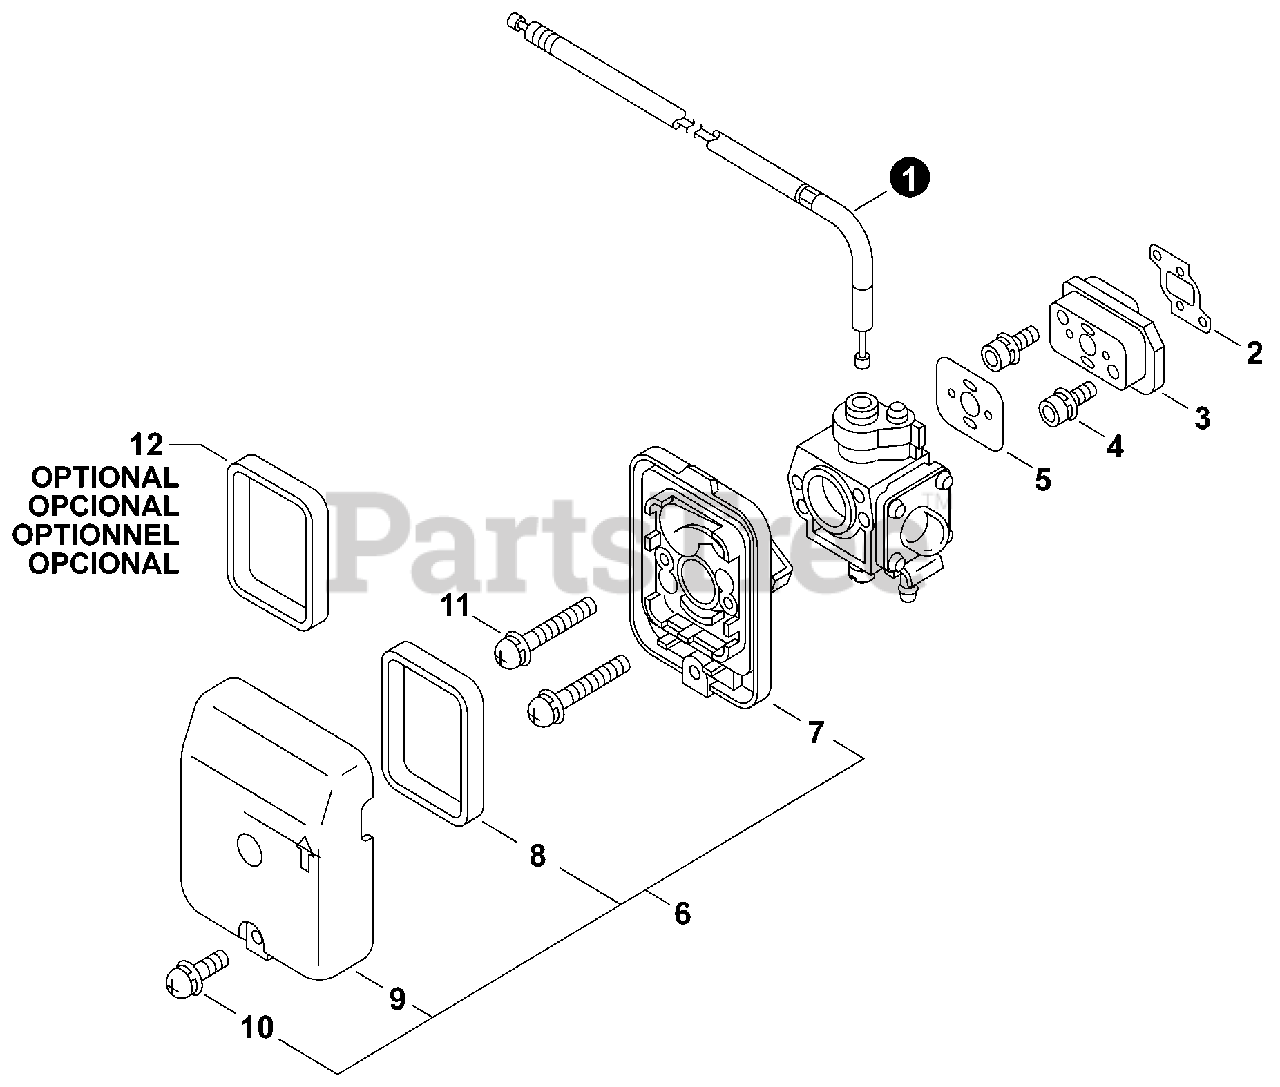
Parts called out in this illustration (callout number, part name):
1	CABLE, THROTTLE
2	GASKET, INTAKE
3	INSULATOR, INTAKE
4	BOLT 5x25
5	GASKET, INTAKE
6	FILTER ASSY, AIR
7	CASE, AIR FILTER
8	FILTER, AIR #30
9	COVER, AIR FILTER
10	SCREW 5x16
11	SCREW 5x50
12	FILTER, AIR - HEAVY-DUTY #70
